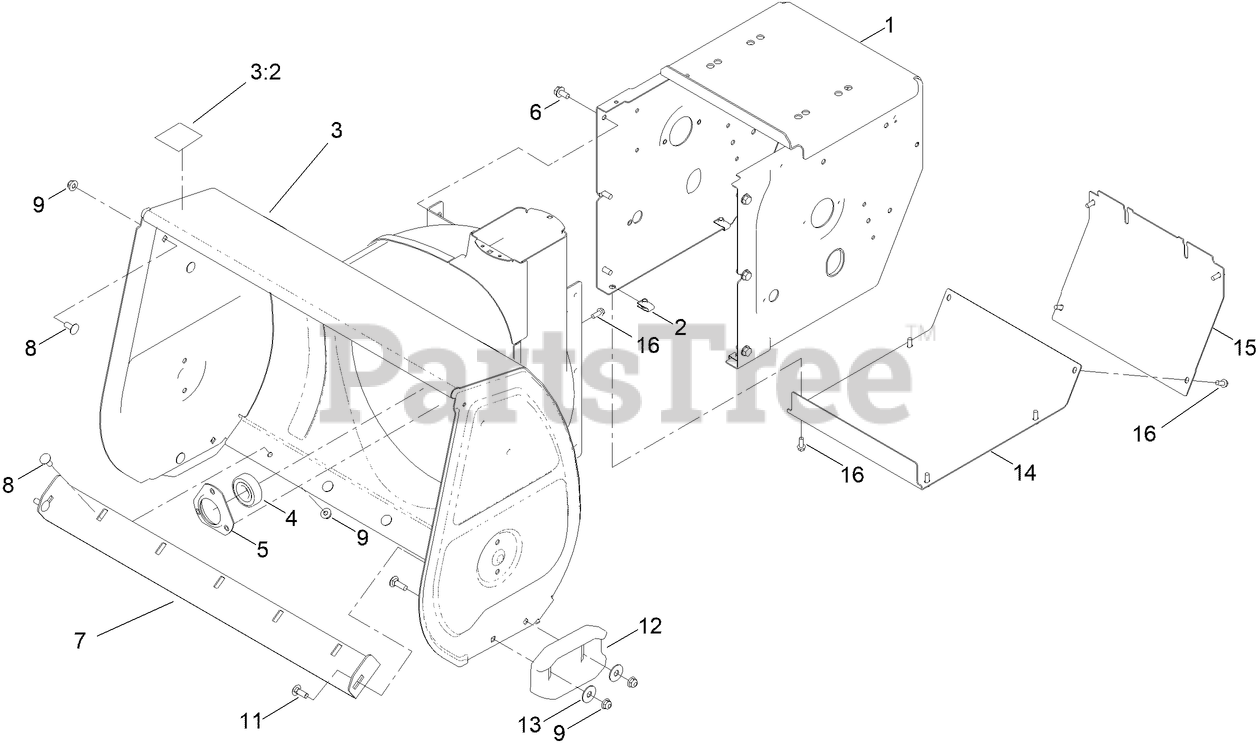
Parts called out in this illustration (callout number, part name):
1	FRAME-TRACTION
3	AUGER HOUSING ASM (W/DECAL 30")
3:2	DECAL-DANGER, AUGER
4	BEARING-BALL
5	RETAINER-BEARING
6	SCREW-HWHTF
7	SCRAPER, 30"
8	BOLT-CARR
9	NUT-HF
11	BOLT-CARR
13	WASHER-FLAT
14	COVER-BOTTOM
15	COVER-REAR
16	SCREW-HWH
